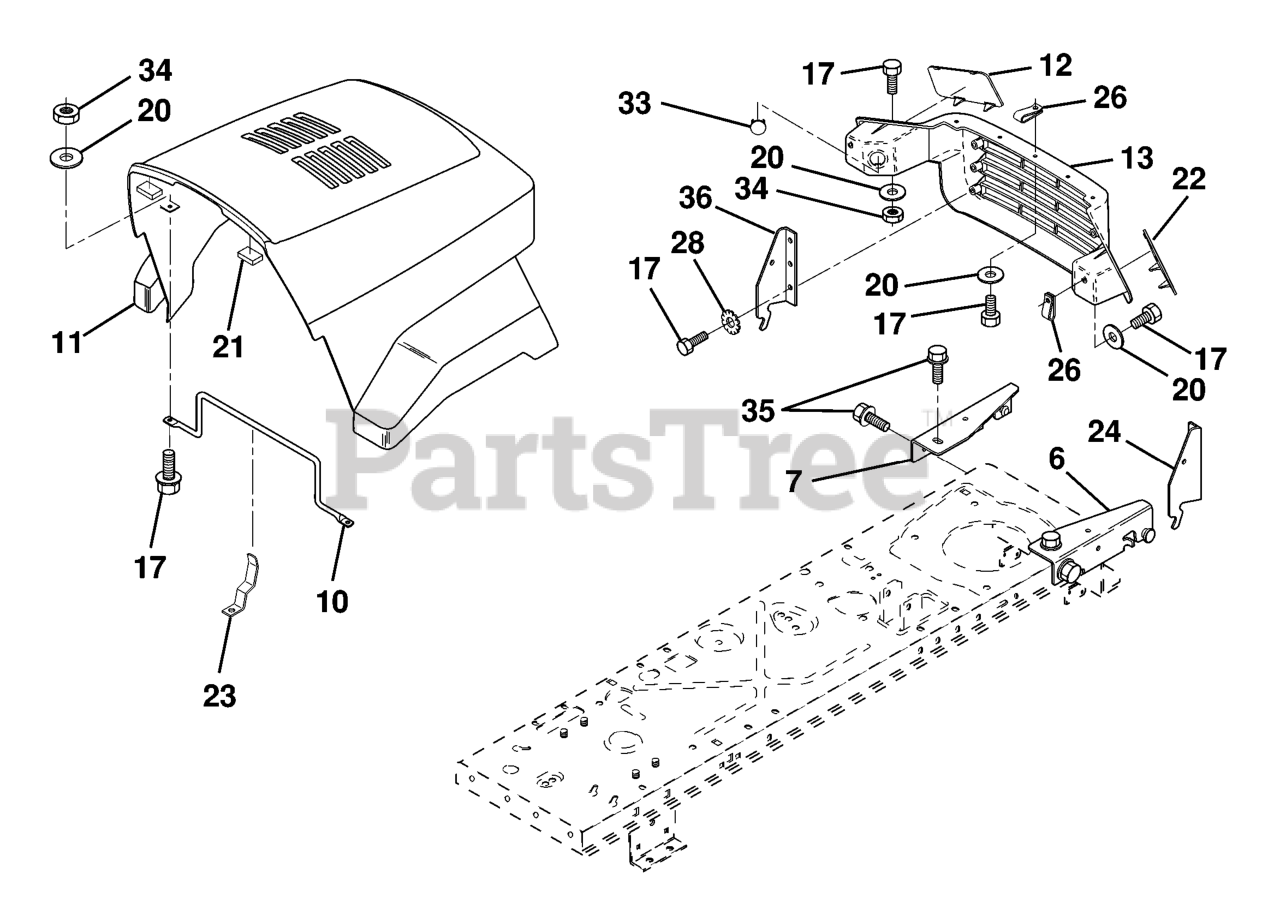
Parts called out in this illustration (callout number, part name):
6	BRACKET ASSY HOOD
7	BRACKET ASSY
10	BRACE HOOD
13	GRILL/HUSQVARNA
17	BOLT
21	BUMPER HOOD T
23	HOOD LATCH
24	BRACKET PIVOT
26	CLIP TINNERMAN
28	Washer, Lock, External Tooth 1/4
33	CVR LIGHT SOCKET
34	NUT.CROWNLOCK.1/4
35	SCREW.THDROL.5/16-18X3/4.TTY
36	BRACKET HOOD
